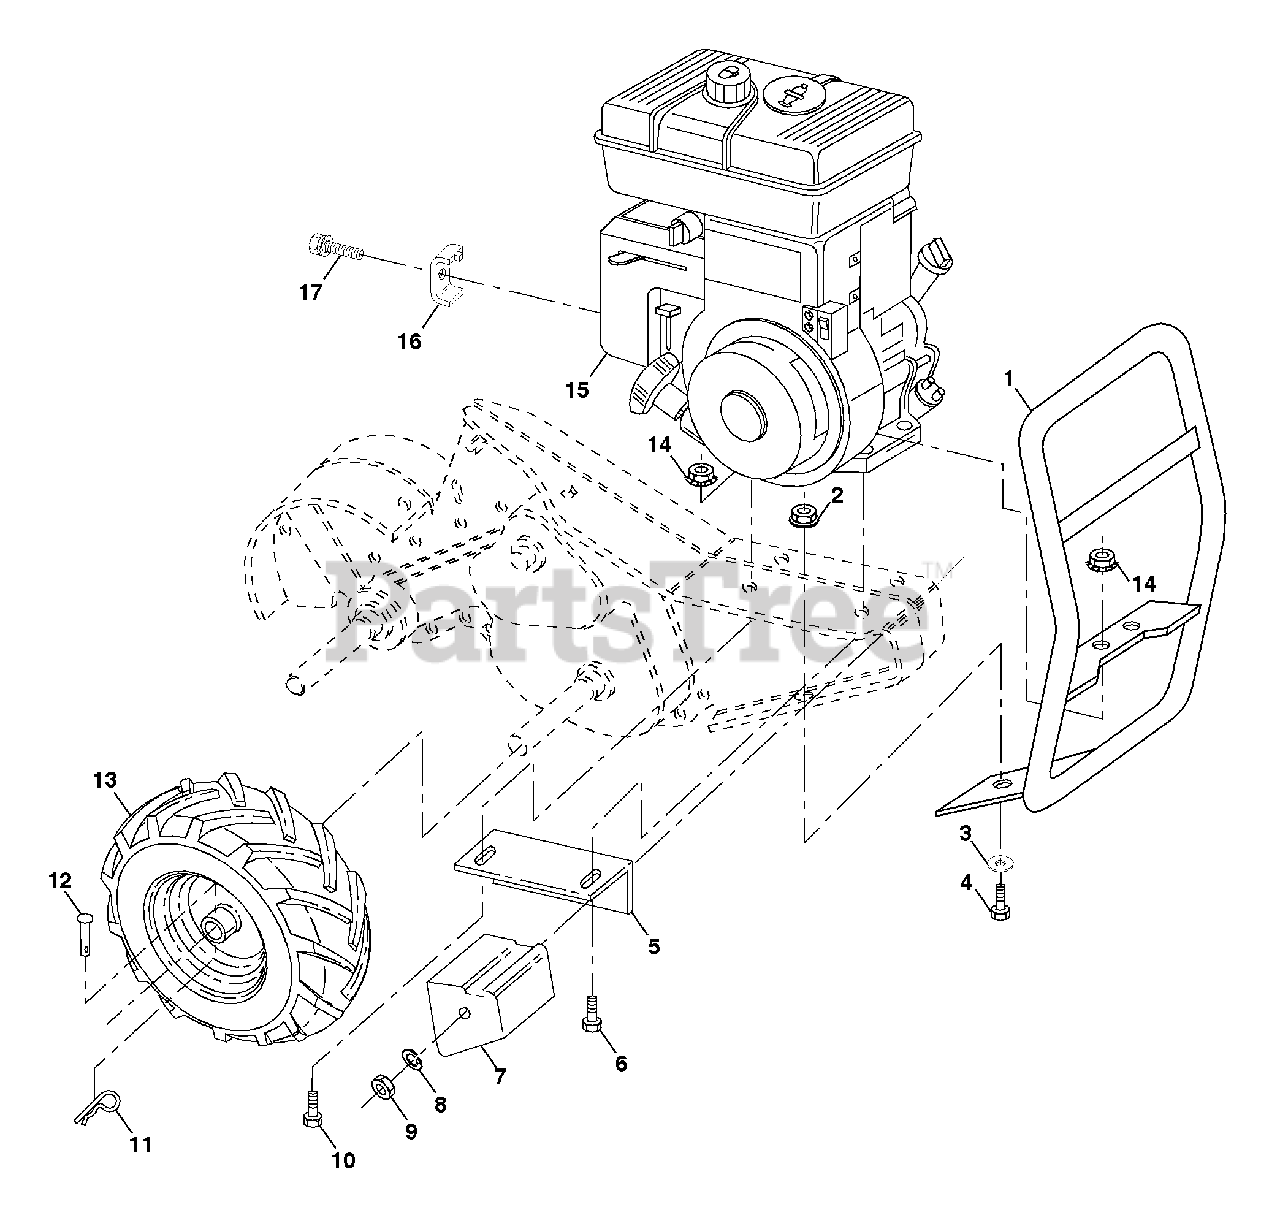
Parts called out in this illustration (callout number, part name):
2	Locknut, Hex, Flange 5/16-18
3	Washer 11/32 x 11/16 x 16 Ga.
4	Bolt, Hex 5/16-18 x 3/4
5	Bracket, Reinforcement
6	Bolt, Hex 5/16-18 x 2
7	Counter Weight, R.H.
8	Washer, Lock 3/8
9	Nut, Hex 3/8-16
10	Bolt, Hex 5/16-18 x 1-1/2
11	Clip, Hairpin
12	Rivet, Drilled
14	Nut, Keps 5/16-18
15	Engine
